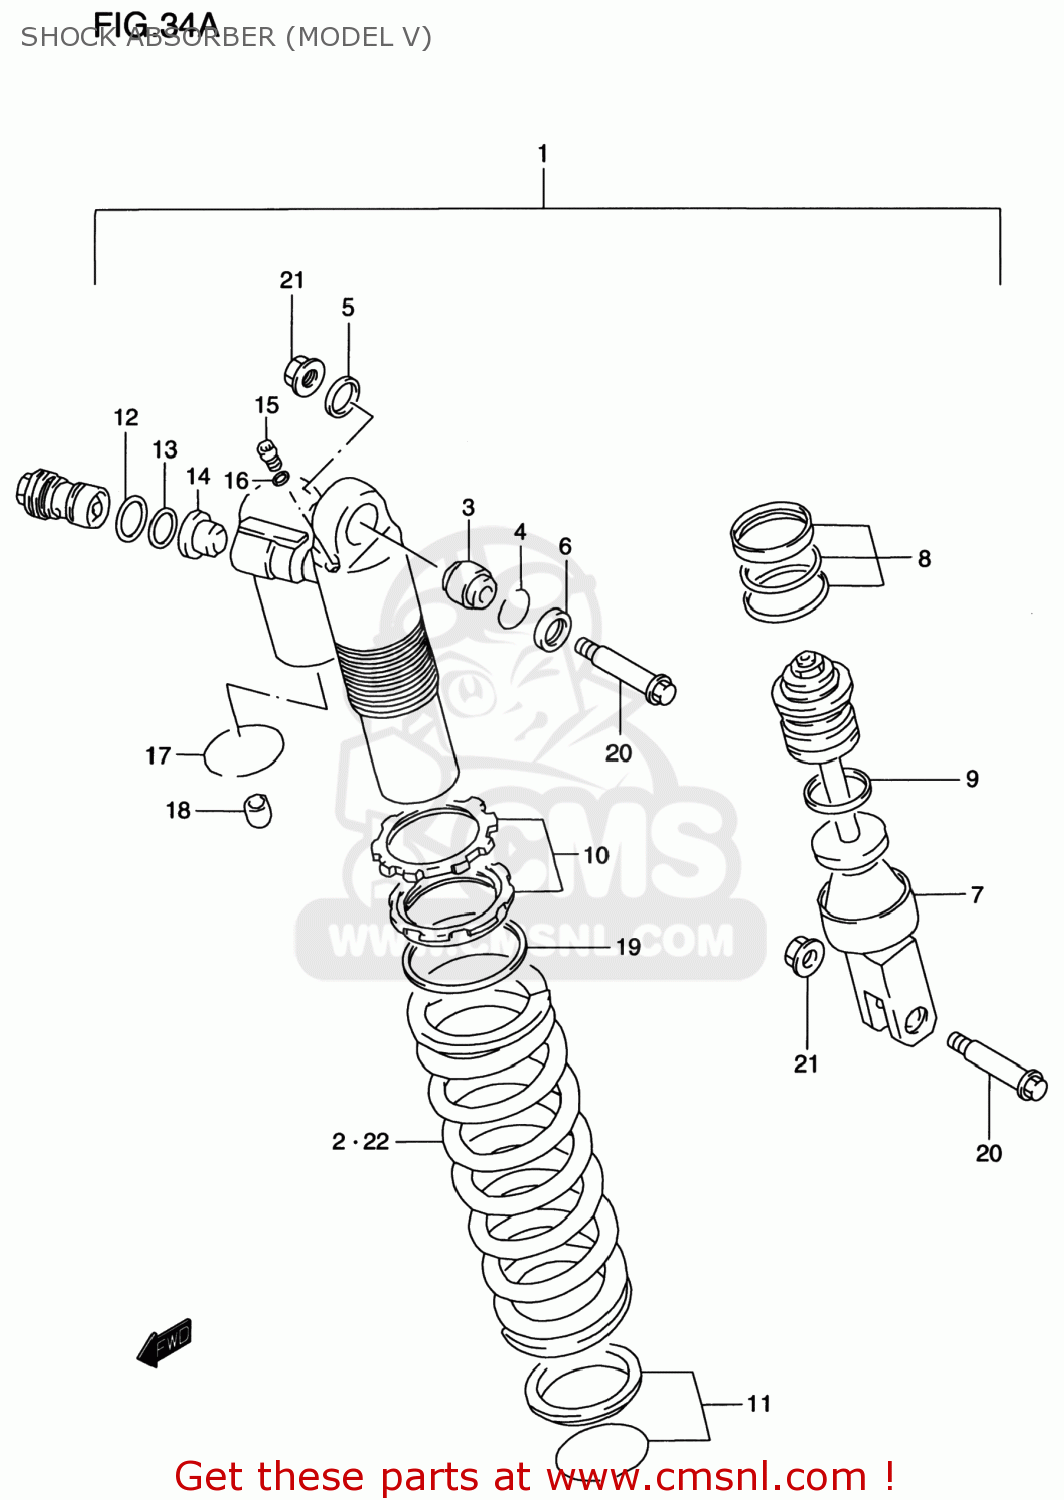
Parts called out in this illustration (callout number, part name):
1	ABSORBER ASSEMBLY,REAR SHOCK
2	SPRING,RR(K=4.8)
3	BEARING,RR SHOCK ABSORBER
4	RING,STOPPER
5	SEAL,DUST UPR,R
6	SEAL,DUST UPR,L
7	ROD,PISTON
8	O RINR SET
9	RING,STOPPER
10	ADJUSTER SET,SHOCK ABSORBER
11	SPRING SEAT SET,SHOCK ABSORBER
12	O RING
13	O RING,CTR BOLT UPR
14	COLLAR,ORIFICE
15	BOLT
16	GASKET,DRAIN,PLUG (NAS)
17	RING,STOPPER
18	CAP
19	SEAT,SPRING
20	BOLT(10X47.5)
21	NUT
22	SPRING,REAR (K=5.0)
